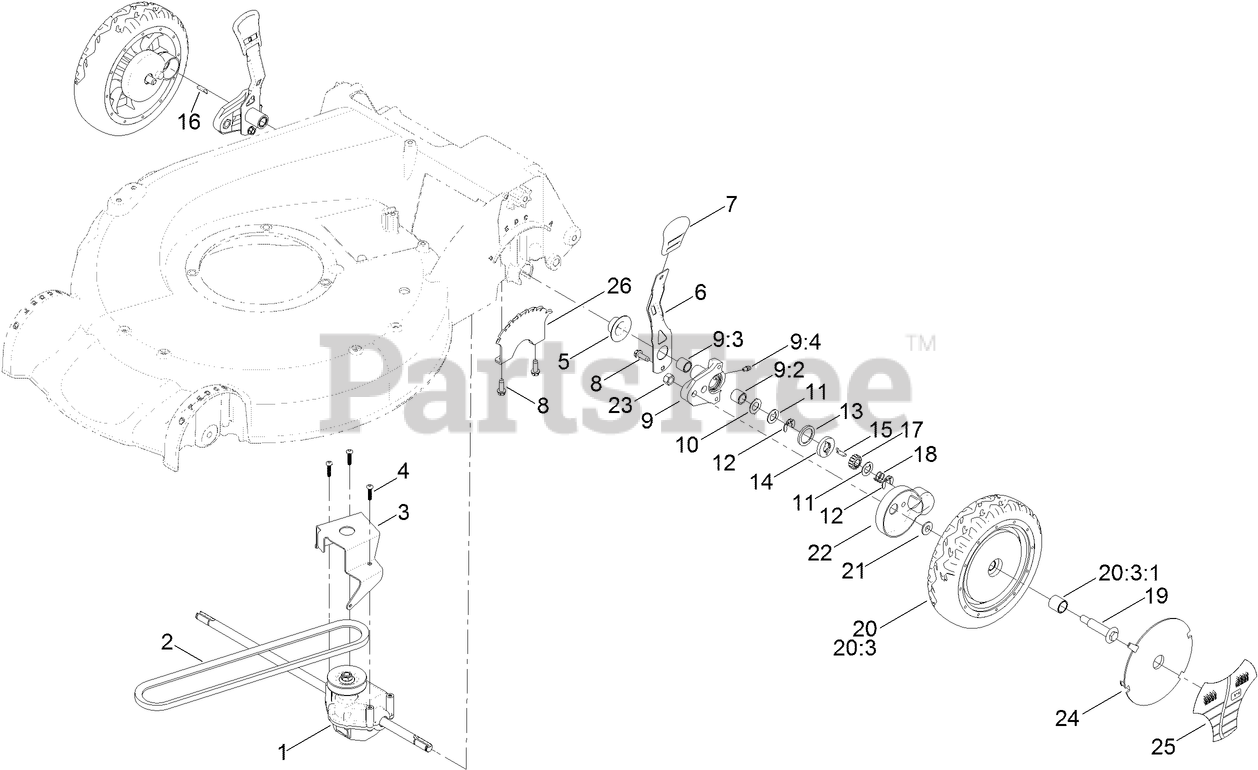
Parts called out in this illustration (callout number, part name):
1	TRANSMISSION ASM
2	V-BELT
3	BRACKET-TRANSMISSION
4	SCREW-PLASTITE
5	CAP-END
6	ARM-SPRING
7	KNOB-HOC
8	SCREW-HWHTF
9	PIVOT ARM ASM
9:2	BUSHING
9:3	BUSHING
9:4	FITTING-GREASE
10	WASHER-ARM, PIVOT
11	WASHER-THRUST, KEYED
12	RING-CLIP, LOCKING
13	RING-FRICTION
14	WASHER-CLUTCH
15	KEY-ROCKING, LH
16	KEY-ROCKING, RH
17	GEAR-PINION
18	SPRING-COMPRESSION
19	BOLT-SHOULDER
20	8 INCH WHEEL AND GEAR ASM
20:3	8 INCH WHEEL ASM
20:3:1	BUSHING
21	SPACER-COVER, WHEEL
22	COVER-WHEEL
23	NUT-HEX
24	COVER-WHEEL
25	LABEL-WHEEL, SMART
26	PLATE-HOC
